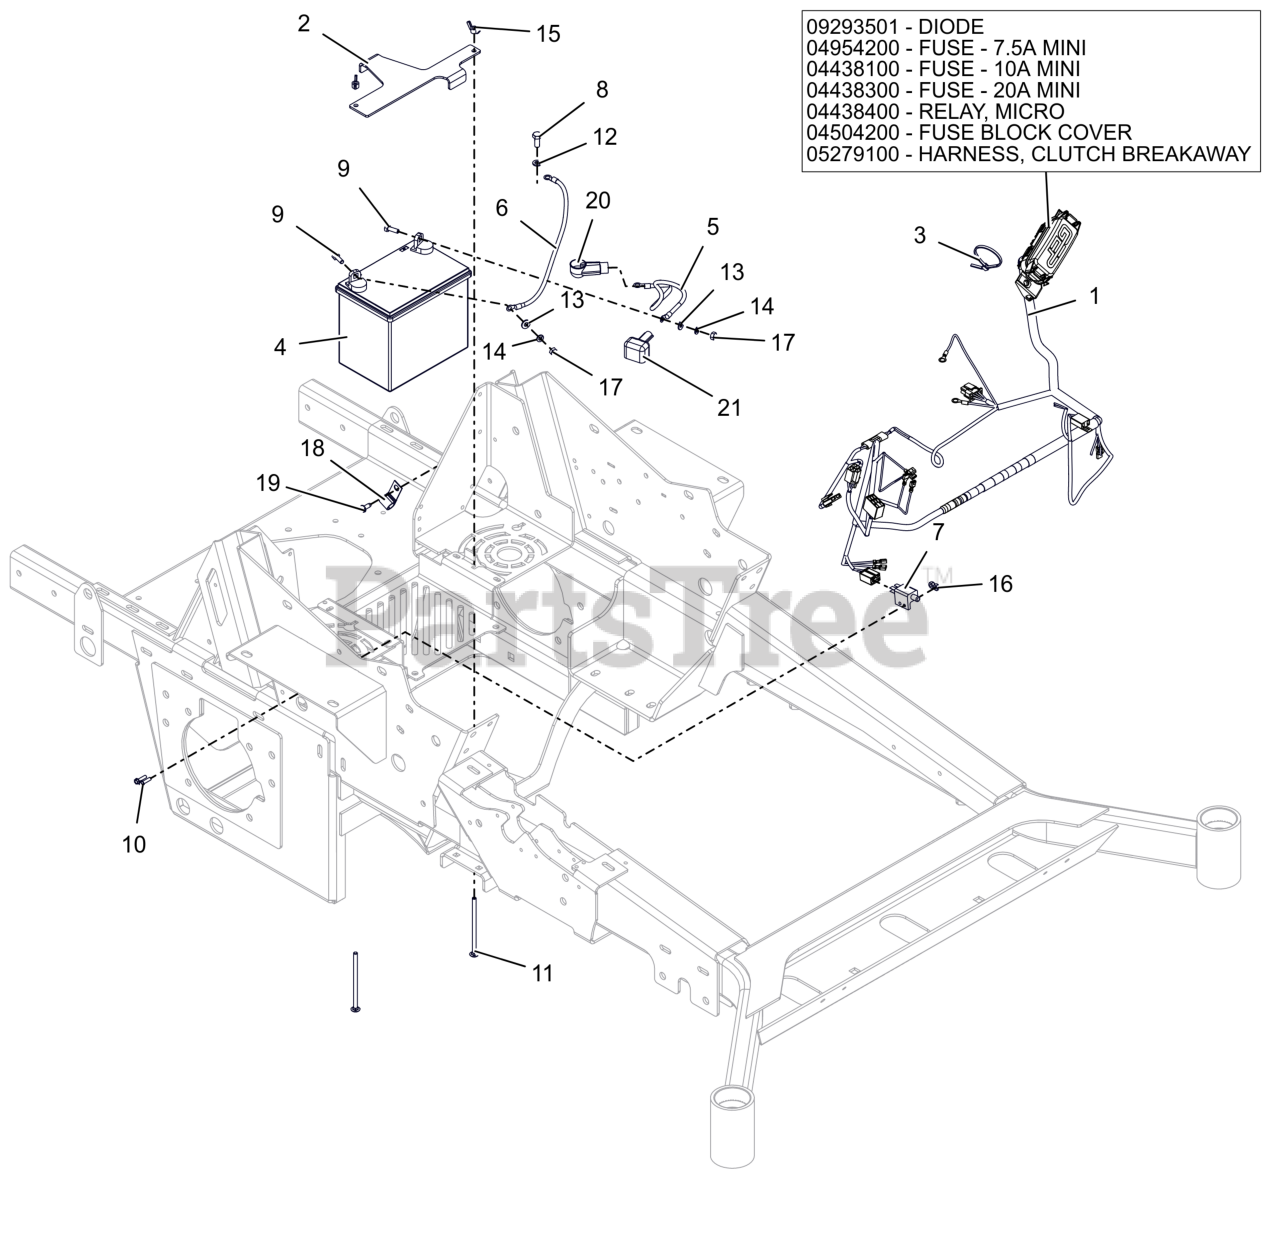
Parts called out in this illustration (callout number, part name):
1	HARNESS- WIRE PT300 MAIN
1	DIODE, CONNECTOR SHELL
1	FUSE, 7.5 AMP MINI-ATC
1	FUSE,10 AMP MINI-ATC
1	FUSE,20 AMP MINI ATC
1	RELAY,MICRO5 TERML W/RESISTOR
1	COVER, HARNESS FUSE/RELAY MOD
1	HARNESS, CLUTCH BREAKAWAY
2	HOLDDOWN- BATTERY
3	CABLE TIE, .15 X 8.50
4	BATTERY, 300 CCA 10U1L
5	CABLE, STARTER 13.00"
6	CABLE-GROUND .25 X 13.00 X .31
7	SWITCH- DOUBLE POLE N.O./N.O.
8	BLT, HEX M8-1.25X20 G8.8 ZCC
9	BLT, HEX .25-20X.75 G5 ZCC
10	BLT, HWH #10-24X.75 ZCC
11	BLT, RHSN .25-20X4.50 G5 ZCC
12	WSHR,LK-REG .312X.078 ZCC
13	WSHR,FLT .281X.625X.065 ZCC
14	WSHR,LK-REG .250X.062 ZCC
15	NUT, LK-WING .25-20 ZCC
16	NUT-LK-NYL #10-24 G2 ZCC
17	NUT-STD .250-20 G2 ZCC
19	SCR,TAP .25-20X.625 HWH ZCC
20	BOOT, .65ID POS
21	INSULATOR
